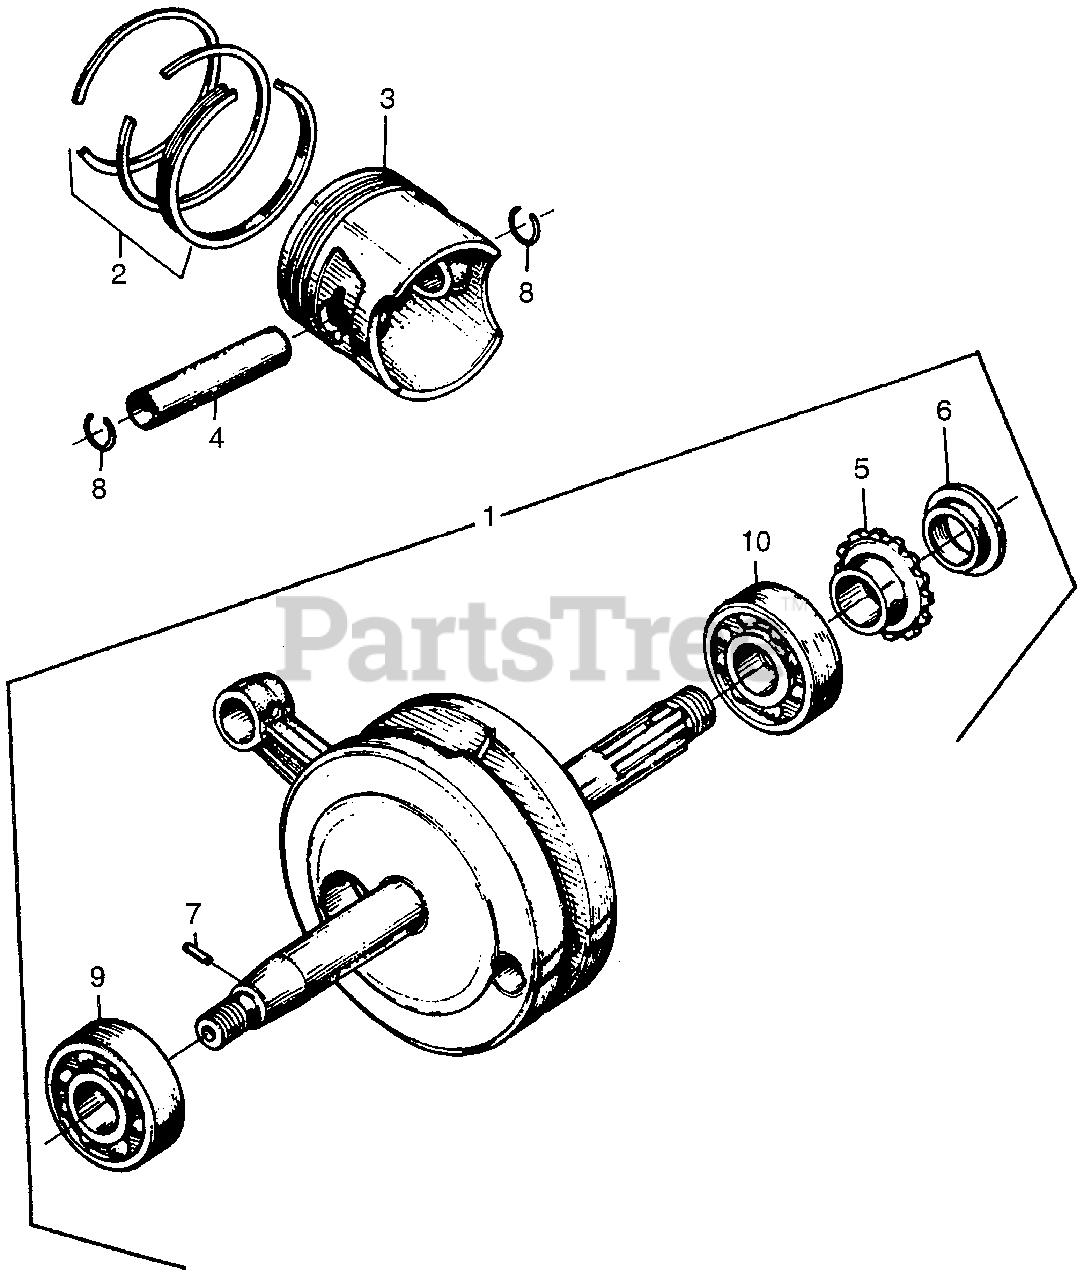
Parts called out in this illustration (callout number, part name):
1	CRANKSHAFT ASSY.
2	RING SET, PISTON (STD)
2	RING SET, PISTON (STD) (NOT AVAILABLE)
2	RING SET, PISTON (OS 0.25)
2	RING SET, PISTON (OS 0.50)
2	RING SET, PISTON (0.75)
4	PIN, PISTON (NOT AVAILABLE)
5	SPROCKET, TIMING (NOT AVAILABLE)
6	COLLAR, SPROCKET (NOT AVAILABLE)
7	KEY, WOODRUFF (3MM)
7	PIN, DOWEL (3X4) (NOT AVAILABLE)
8	CLIP, PISTON PIN (13MM)
9	BEARING, RADIAL BALL (6203)
10	BEARING, RADIAL BALL (6303)
